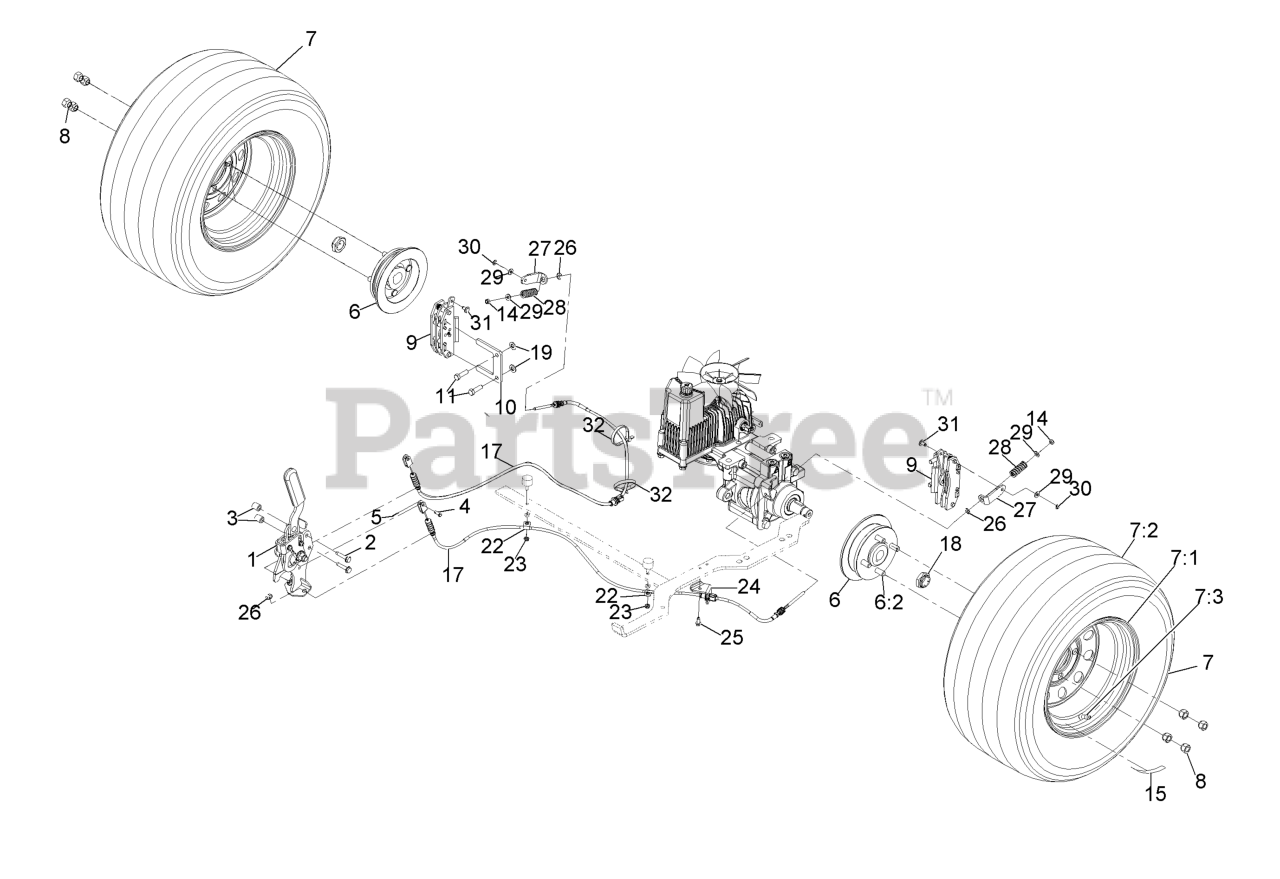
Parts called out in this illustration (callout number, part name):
1	BRAKE HANDLE ASM
4	PIN-CLEVIS
5	PIN-COTTER
6	WHEEL HUB ASM
6:2	STUD-WHEEL
7	WHEEL AND TIRE ASM
7:3	Stem-Valve
8	NUT-LUG
9	CALIPER-BRAKE
10	PLATE-MOUNT, BRAKE
11	SCREW-LOCK, PATCH
14	NUT-LOCK, NI
18	LOCKNUT
19	WASHER-FLAT
23	NUT-LOCK, NI
24	BRACKET-CABLE
25	SCREW-HWH
27	BRACKET-BRAKE, L
28	SPRING-DIE
29	WASHER-FLAT
31	PIN-BRAKE
32	TIE-CABLE
